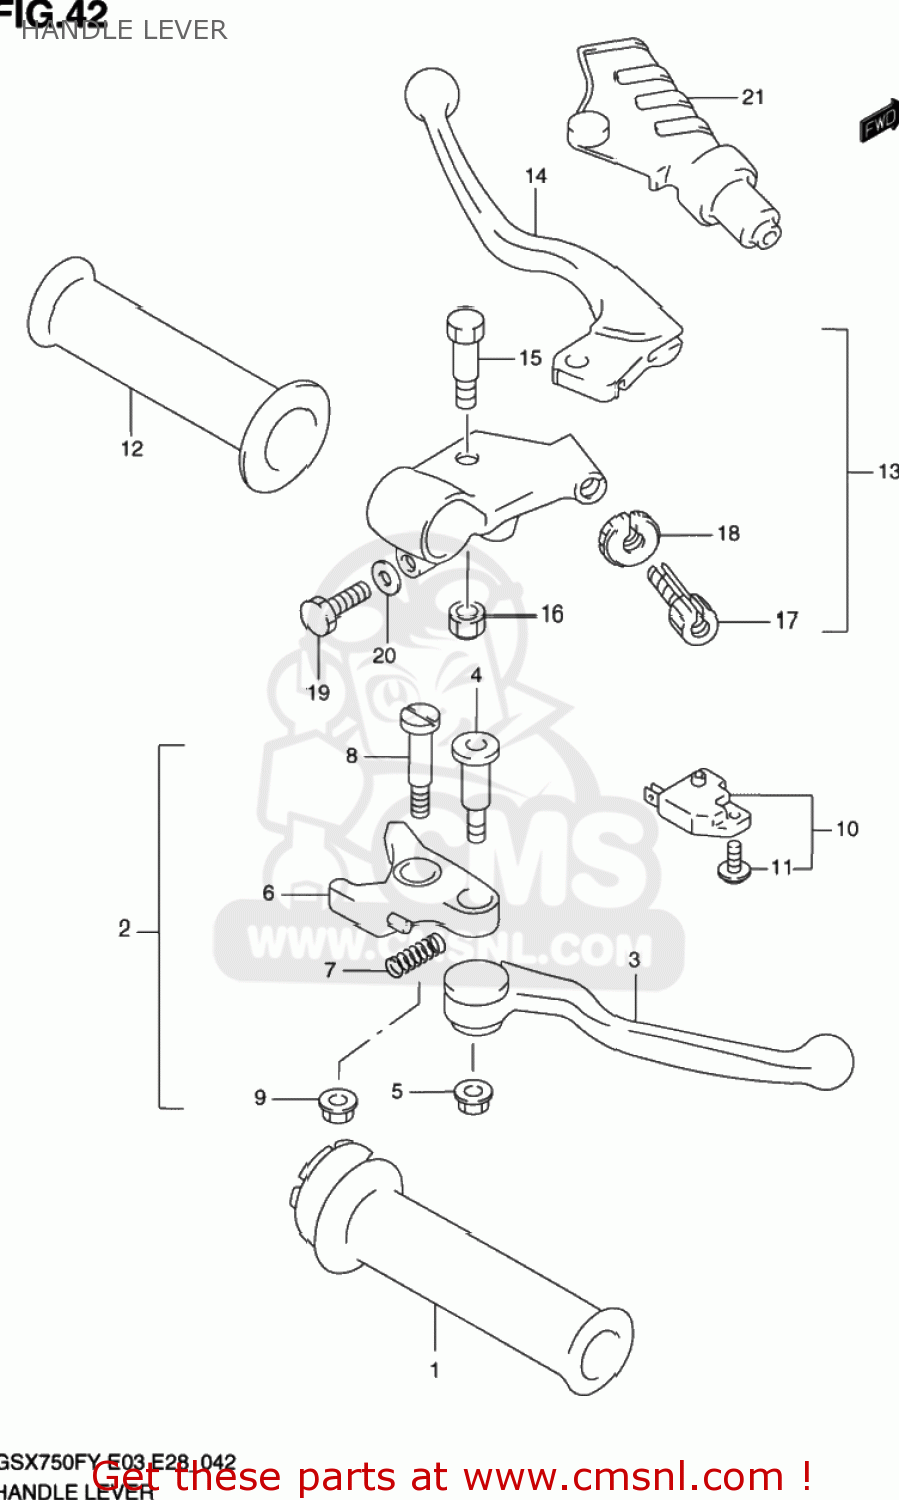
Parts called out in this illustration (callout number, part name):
1	GRIP,THROTTLE
2	LEVER ASSY,BRAKE
3	LEVER,ADJUST
4	BOLT,LEVER
5	NUT
6	KNOCKER
7	SPRING
8	BOLT,LEVER PIVOT
9	NUT
10	SWITCH ASSEMBLY,STOP
11	SCREW
12	GRIP,LEFT
13	LEVER ASSY,CLUTCH
14	LEVER,CLUTCH
15	BOLT,LEVER SET
16	NUT
17	ADJUSTER,CABLE
18	NUT,CABLE ADJUSTER
19	BOLT
20	WASHER
21	COVER,CLUTCH LEVER
